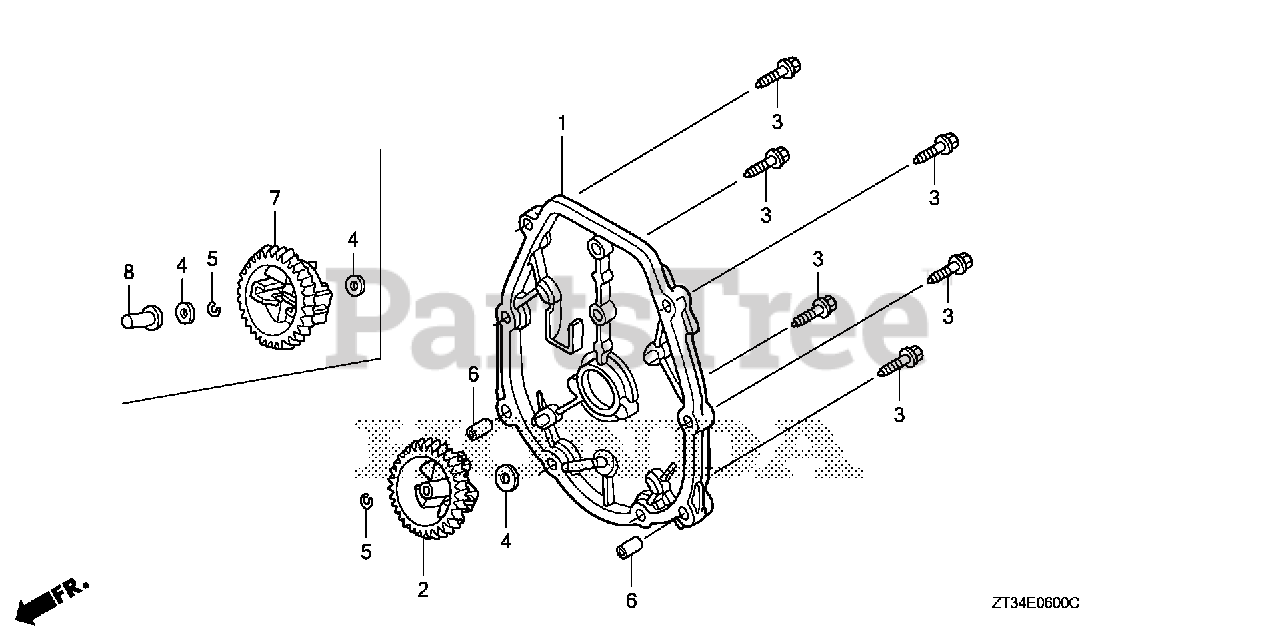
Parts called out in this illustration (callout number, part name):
1	COVER, CRANKCASE SIDE
2	HOLDER, GOVERNOR WEIGHT
3	BOLT, FLANGE (5X23)
4	WASHER (4.2X13)
5	CLIP, GOVERNOR HOLDER
6	PIN, DOWEL (6X10)
